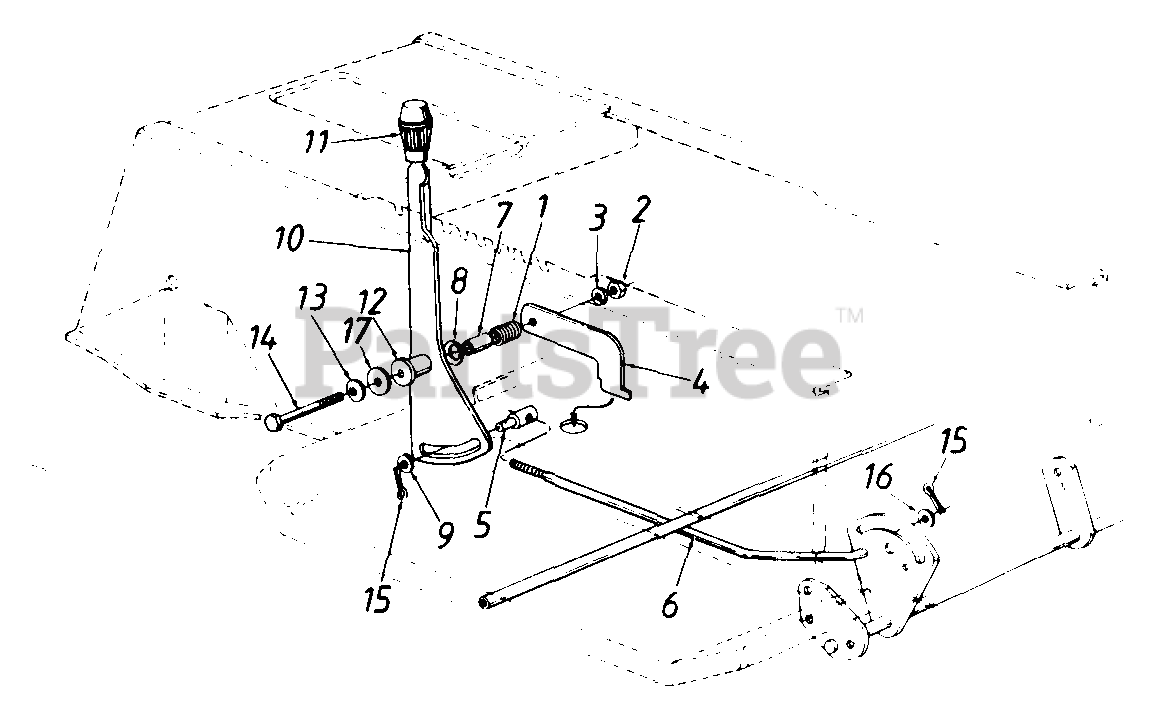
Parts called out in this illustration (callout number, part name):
1	Compression Spring
2	Hex Nut 5/16-18 Thd.
3	L-Wash. 5/16" I.D.
4	Shift Lever Support
5	Ferrule 3/8-24 Thd.
6	Speed Control Rod
7	Spacer 1.56" Lg.
8	Bell-Wash..505" I.D. x 1" O.D.
9	Fl-Wash..385" I.D. x .87" O.D.
10	Speed Selector Lever
11	Shift Knob
12	Spacer 1.46" Lg.
13	Bell-Wash..345" I.D. x .88" O.D.
14	Hex Bolt 5/16-18 x 3.25" Lg.
15	Cotter Pin 3/32" Dia. x 1" Lg.
16	Fl-Wash..469" I.D. x .88"
17	Fl-Wash..34" I.D. x 2.25"
